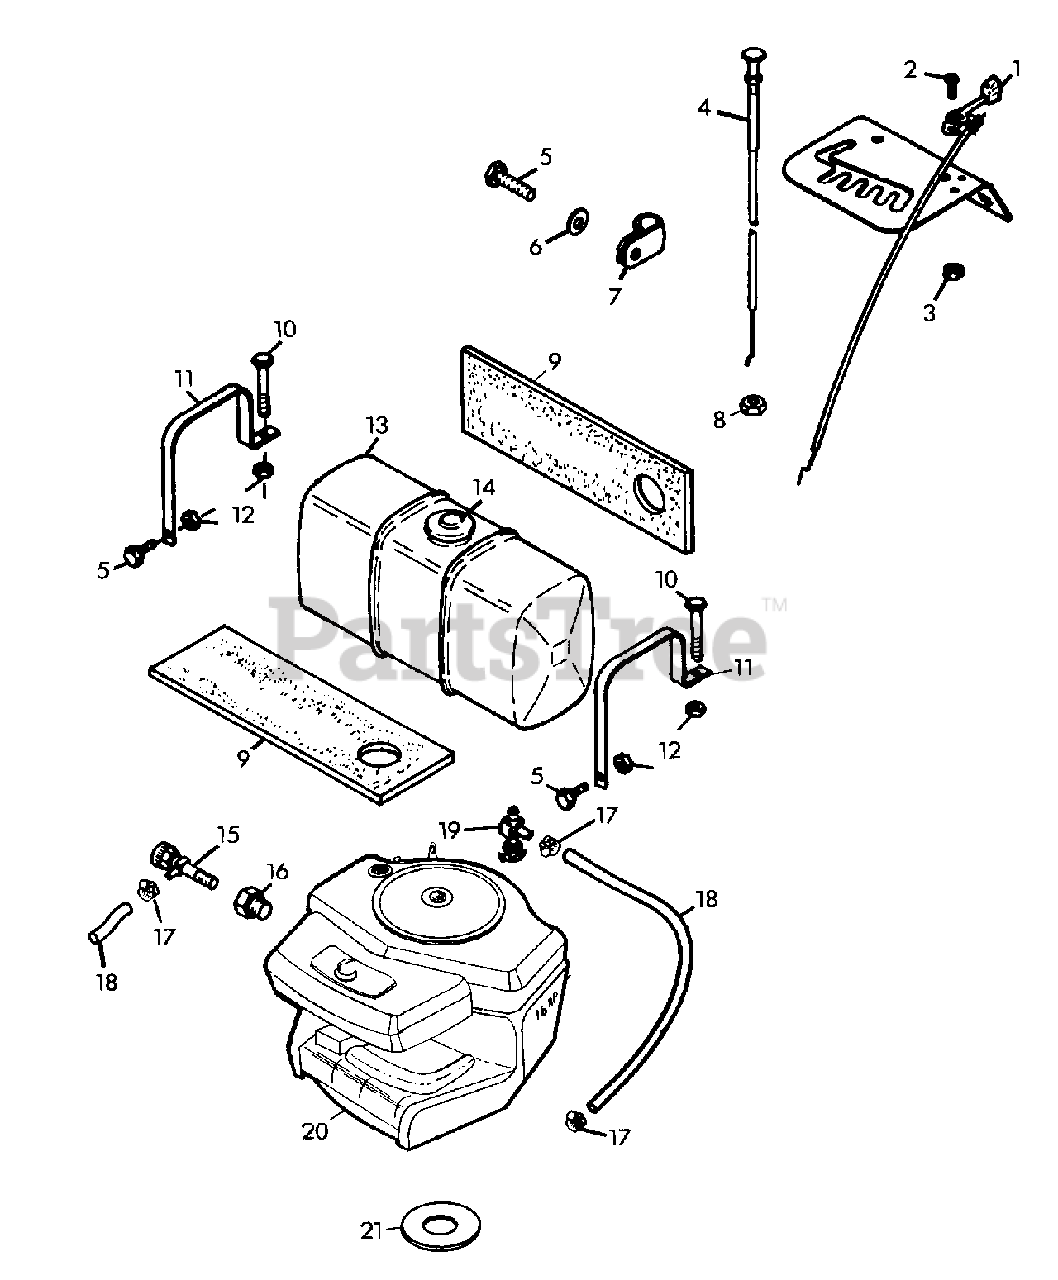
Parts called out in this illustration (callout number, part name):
1	LEVER, CONTROL
2	SCREW, MACH. 10-24X.50 PHD
3	NUT, LOCK 10-24
4	CONTROL, CHOKE
5	BOLT, HEX 1/4-20X.625
6	WASHER, FLAT .281X.625X.065
7	CLAMP
8	NUT, JAM 3/8-24 HEX
9	PAD, GAS TANK
10	BOLT, HEX 1/4-20X1.75
11	STRAP, FUEL TANK
12	NUT, LOCK 1/4-20
13	TANK, FUEL (12 QTS.)
14	CAP, GAS TANK
15	COCK, OIL DRAIN
16	ADAPTOR, OIL DRAIN
17	CLAMP, HOSE
18	LINE, FUEL
19	VALVE AND STRAINER
20	ENGINE, 16 H.P. B&S
21	WASHER, FLAT
